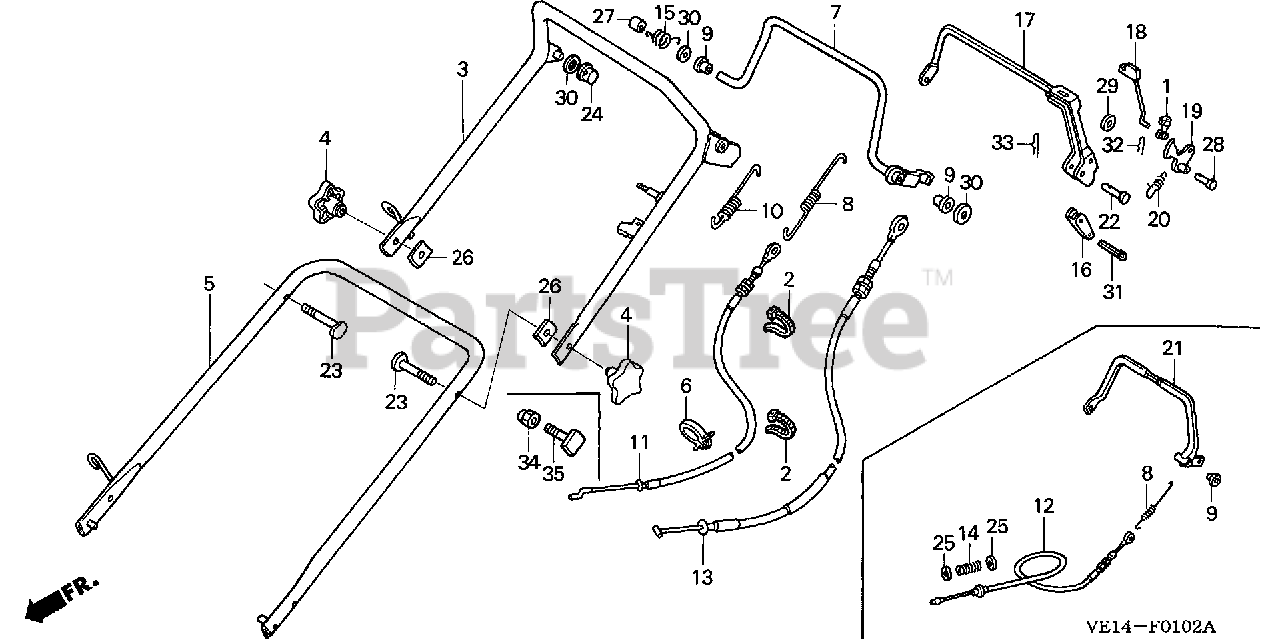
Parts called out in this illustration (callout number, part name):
1	JOINT, ROD
2	TIE, CABLE (157.5MM)
3	PIPE, HANDLE (UPPER) *NH105* (MAT BLACK)
4	GRIP, HANDLE JOINT (UPPER)
5	HANDLE (LOWER) *NH105* (MAT BLACK)
7	LEVER, CLUTCH
8	SPRING, CLUTCH
9	BUSH, CLUTCH LEVER
10	SPRING, CLUTCH LEVER RETURN
13	CABLE, ROTO-STOP
15	SPRING, R. STOP RETURN
16	ARM, ROTO-STOP CABLE
17	LEVER, ROTO-STOP
18	ROD, RATCHET PUSH
19	LEVER, LOCK
20	SPRING, RATCHET RETURN
22	PIN, CLUTCH LEVER
26	WASHER, FRAME JOINT
27	COLLAR (8X11X13.5)
28	PIN, LOCK LEVER HINGE (6X30)
29	WASHER, PLAIN (6MM)
30	WASHER, PLAIN (8MM)
31	PIN, SPLIT (2.0)
32	PIN, LOCK (6MM)
33	PIN, LOCK (8MM)
34	NUT, CAP (8MM)
35	BOLT, HANDLE HOLDER (8X36)
